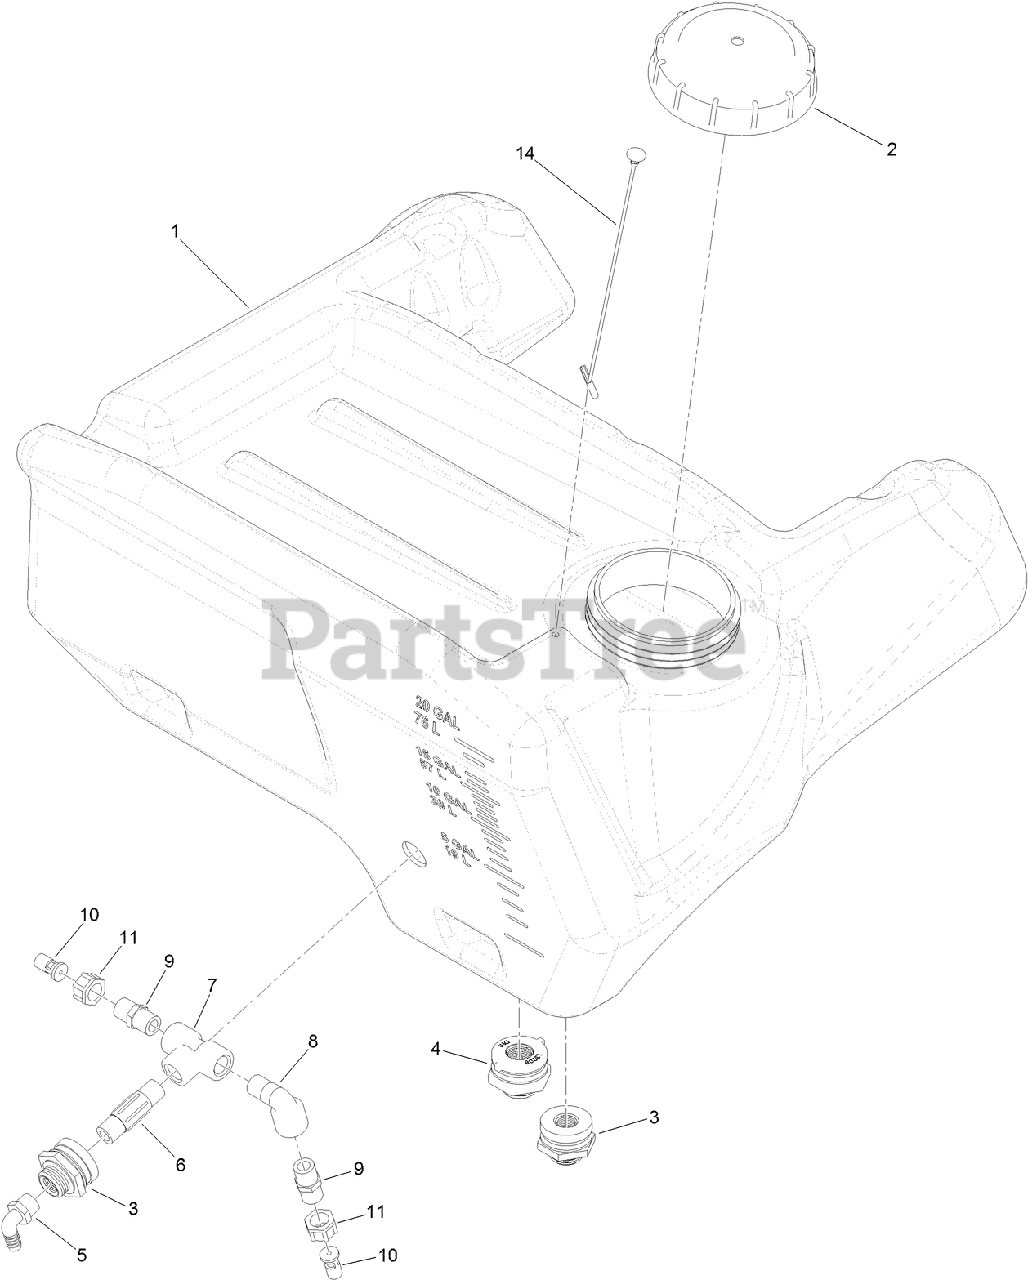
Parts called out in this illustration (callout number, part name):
1	TANK-SPRAYER
2	CAP-WATER, 5 INCH VENT
3	FITTING-BULKHEAD
4	FITTING-BULKHEAD
5	ELBOW-90 DEG
6	NIPPLE
8	ELBOW-90 DEG
9	NIPPLE-SHORT
10	NOZZLE-AGITATION
14	LANYARD-CAP, SELF ANCHORING (12 INCH)
